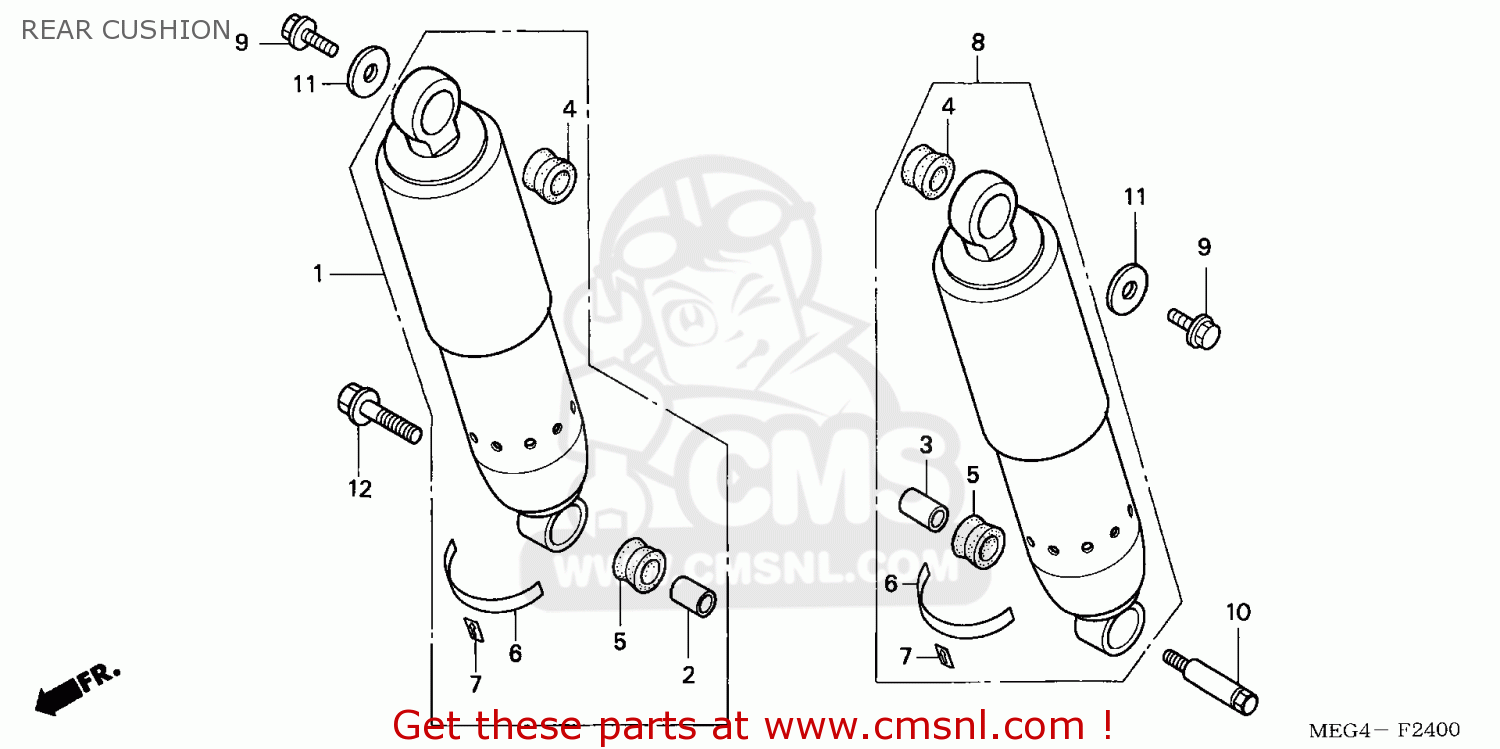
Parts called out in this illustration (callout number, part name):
1	CUSHION ASSY RR
2	COLLAR
3	COLLAR
4	BUSH,RR.CUSH UPPE
5	BUSH,RR.CUSHION
6	LABEL.RR.DAMPER
7	LABEL,POSITION
8	CUSHION ASSY RR
9	BOLT,FLG,8X16
10	BOLT,RR CUSHION
11	WASHER,8.5X26
12	BOLT,FLANGE,10X35
